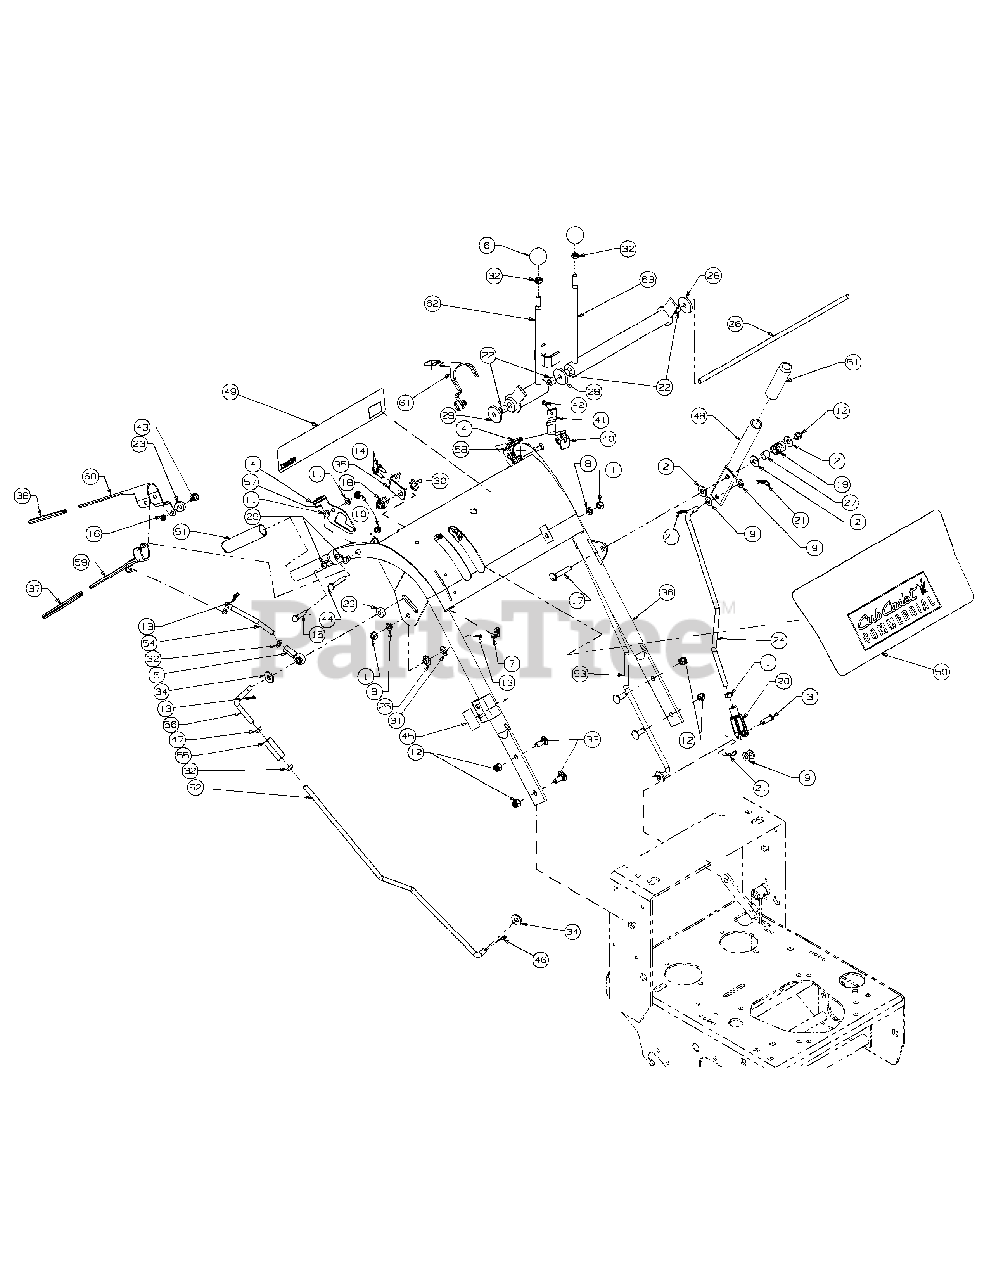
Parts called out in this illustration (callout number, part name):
1	Hex Nut, 3/8 - 16
2	Flat Washer, SS, 3/8
3	Clevis Pin, 3/8 x 1 1/8
4	Grip, 1.25, Black Neutral Lock
5	End Rod, 3/8
6	Knob, 1-3/8 x 1-19/64, 3/8-24
7	Lock Nut, Nylon Insert, 1/4-20
8	Lock Washer, 3/8 Zinc
9	Flat Washer, 3/8, SAE
10	Nut, 5/16-18
11	Flat Washer, SAE 5/16
12	Lock Nut, Nylon Insert, 3/8-16
13	Cotter Pin, 5/32 x 1-1/2 Zinc
14	HHCS, 1/4-20, .75
15	HHCS, Standard, 5/16-18 x 2
16	Lock Nut, Nylon Insert, 1/4 - 28
17	Carriage Bolt, 3/8 -16 x 2
18	Switch Operator’s Presence
19	Spring, .850
20	Yoke, 3/8 - 16, Female
21	Hair Pin, 3/8 - 1/2
22	Bushing, 9/16 OD x 3/8 ID x 1/2
23	Hydro, Spacer Control Rod
24	Blade Clutch, Hydro Rod Base
25	Hydro Bush Control Rod
26	Hydro Rod, Speed Control
27	Sleeve Spring, 32/36/48
28	Friction Washer
29	Nylon Bushing
30	Hex Nut, Dead Man Switch
31	Washer, .469 ID x .875 OD x .105
32	Hex Jam Nut, 3/8-24
33	Carriage Bolt, 3/8 -16 x 2
34	Flat Washer .406 ID x 1.00 OD
35	Mounting Switch, Neutral, Safety
36	Hydro, Handle Assembly
37	Control Sleeve, Drive Black
38	Operators Control Sleeve, Yellow
39	Harness Adapter Assembly
40	Snap Mounting Switch
41	Retension Spring
42	Screw, TT, 10-24, .5
43	Shoulder Screw, .38 x .412, 1/4-28
44	HHCS, 5/16-18, 2.00
45	Parking Brake Decal
46	Cotter Pin Internal, .072 x 1.12
47	Left Hand Threaded Jam Nut, 3/8-24
48	Clutch Lever Blade
49	Lable Handle
50	Panel Label
51	Black Handle Thin Grip
52	Large Right Control Rod
53	Large Left Control Rod
54	Short Control Rod
55	Turnbuckle
56	Upper Control Rod
57	Latch, RH, Neutral Hydro
58	Latch, LH, Neutral Hydro
59	Control Lever Assembly
60	Operator Presence Control Handle, RH
61	Operator Presence Control Handle, LH
62	Control Assembly, Speed Hydro, RH
63	Control Assembly, Speed Hydro, LH
